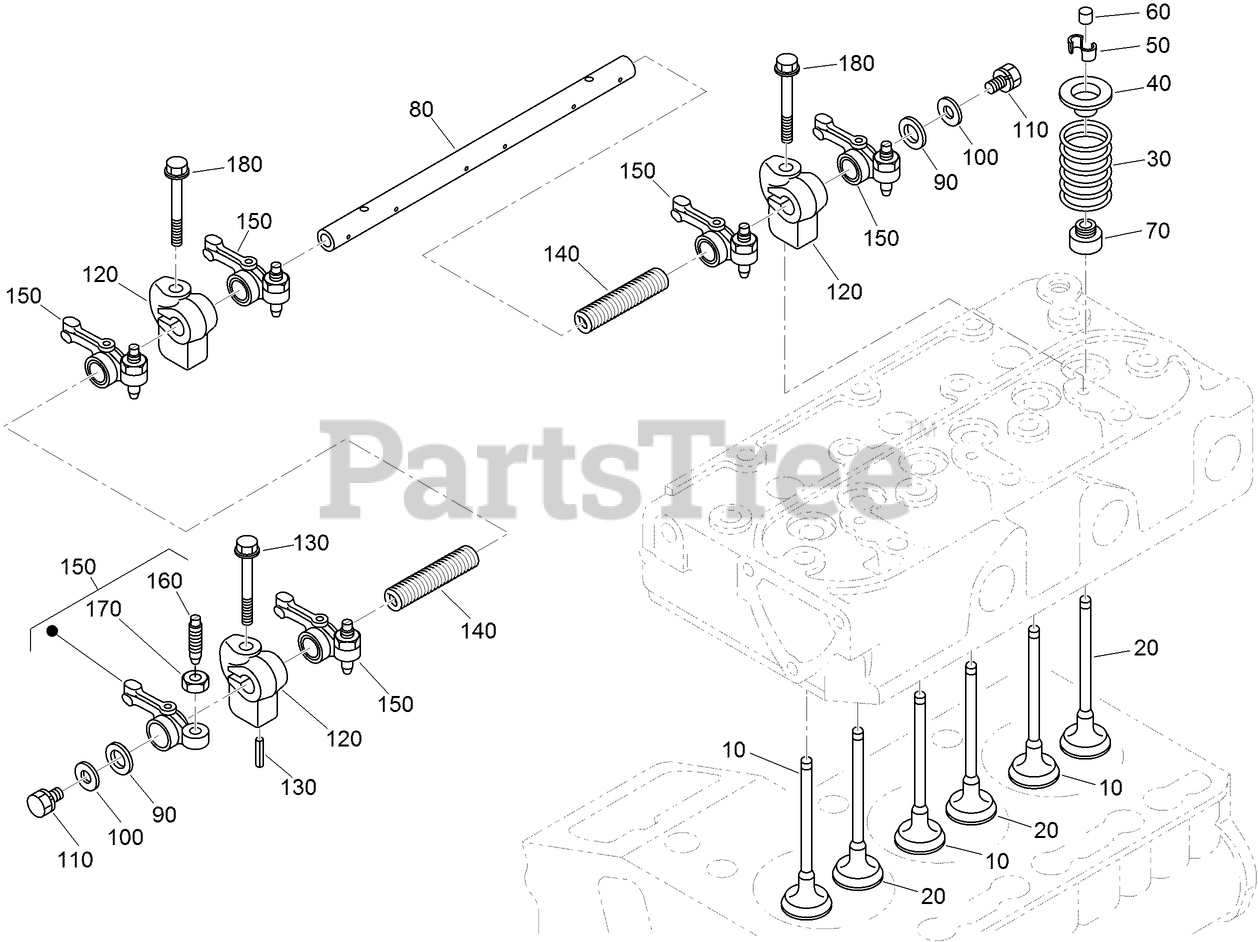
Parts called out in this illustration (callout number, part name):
10	VALVE-INLET
20	VALVE-EXHAUST
30	SPRING-VALVE
40	RETAINER-SPRING, VALVE
50	COLLET-SPRING, VALVE
60	CAP-VALVE
70	SEAL-STEM, VALVE
80	SHAFT-ARM, ROCKER
90	WASHER
100	WASHER-PLAIN
120	BRACKET-ARM, ROCKER
130	PIN-SPRING
140	SPRING
150	ROCKER ARM ASM
160	SCREW-ADJUSTING
180	BOLT-FLANGE
